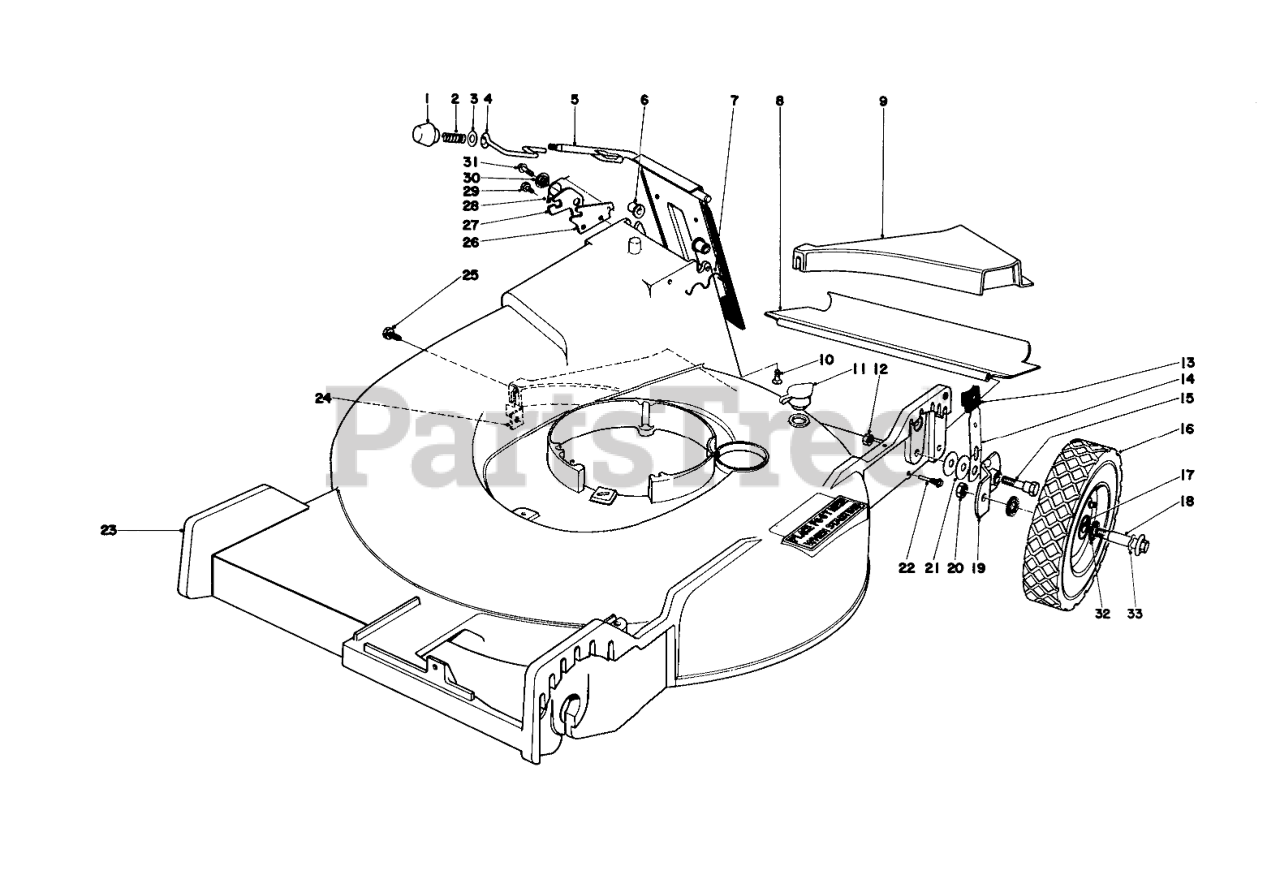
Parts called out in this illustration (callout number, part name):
2	COMPRESSION SPRING
3	WASHER
4	DOOR LATCH
5	Door Handle
6	BUSHING-NYLON
7	Door Retainer
8	REAR SAFETY SHIELD
9	REAR INSERT
10	SCREW-HH
11	WASHOUT PLUG
12	Nut
13	KNOB-ARM
14	SPRING ARM ASM
15	PIVOT SCREW
16	Wheel & Tire Assembly Rear (Incl. Ref. #17)
17	BEARING-BALL
19	PIVOT ARM ASM A
20	Nut
21	WASHER-PIVOT
22	SAFTEY SHIELD SCREW
23	Housing
24	SPECIAL NUT
25	SCREW THD 1/4 20 5/8
26	DOOR LATCH PLATE
27	Latch Safety
28	TORSION SPRING
29	Screw
30	Latch Spacer
31	Screw
32	FELT WASHER
33	SPRING WASHER
